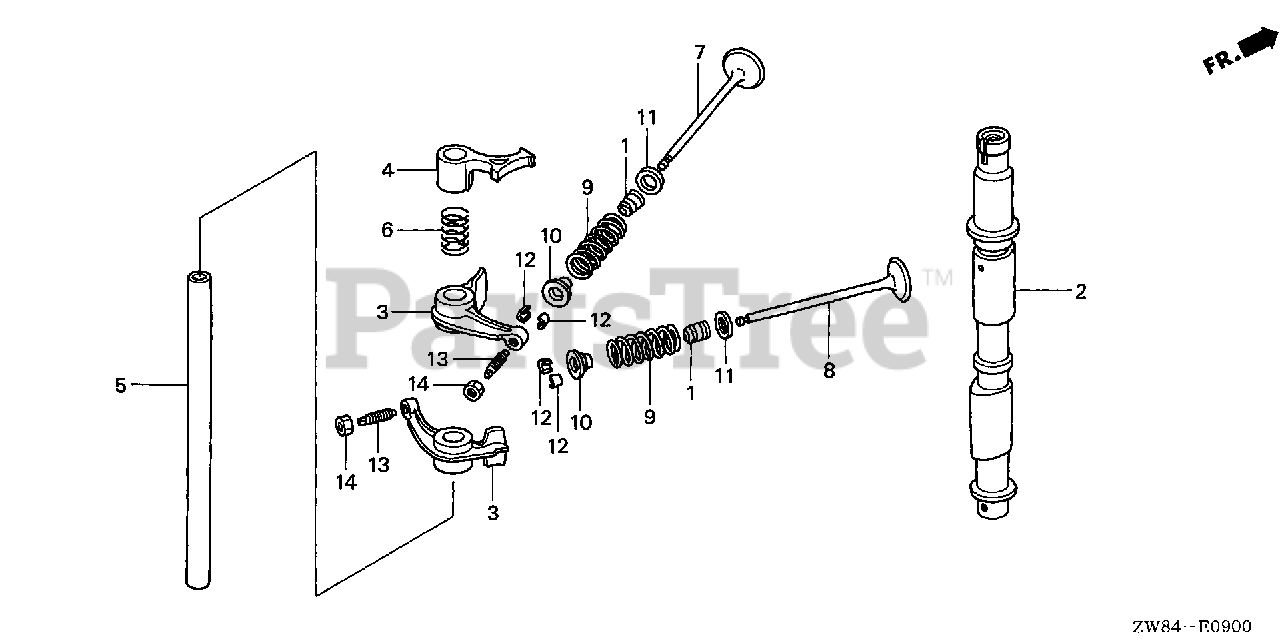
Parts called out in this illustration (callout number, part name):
1	SEAL, VALVE STEM (NOK)
3	ARM, VALVE ROCKER
4	ARM, FUEL PUMP ROCKER
5	SHAFT, ROCKER ARM
6	SPRING, ROCKER ARM
7	VALVE, IN.
8	VALVE, EX.
9	SPRING, VALVE
10	RETAINER, VALVE SPRING
11	SEAT, VALVE SPRING
12	COTTER, VALVE
13	SCREW, TAPPET ADJ.
14	NUT, TAPPET ADJ.
